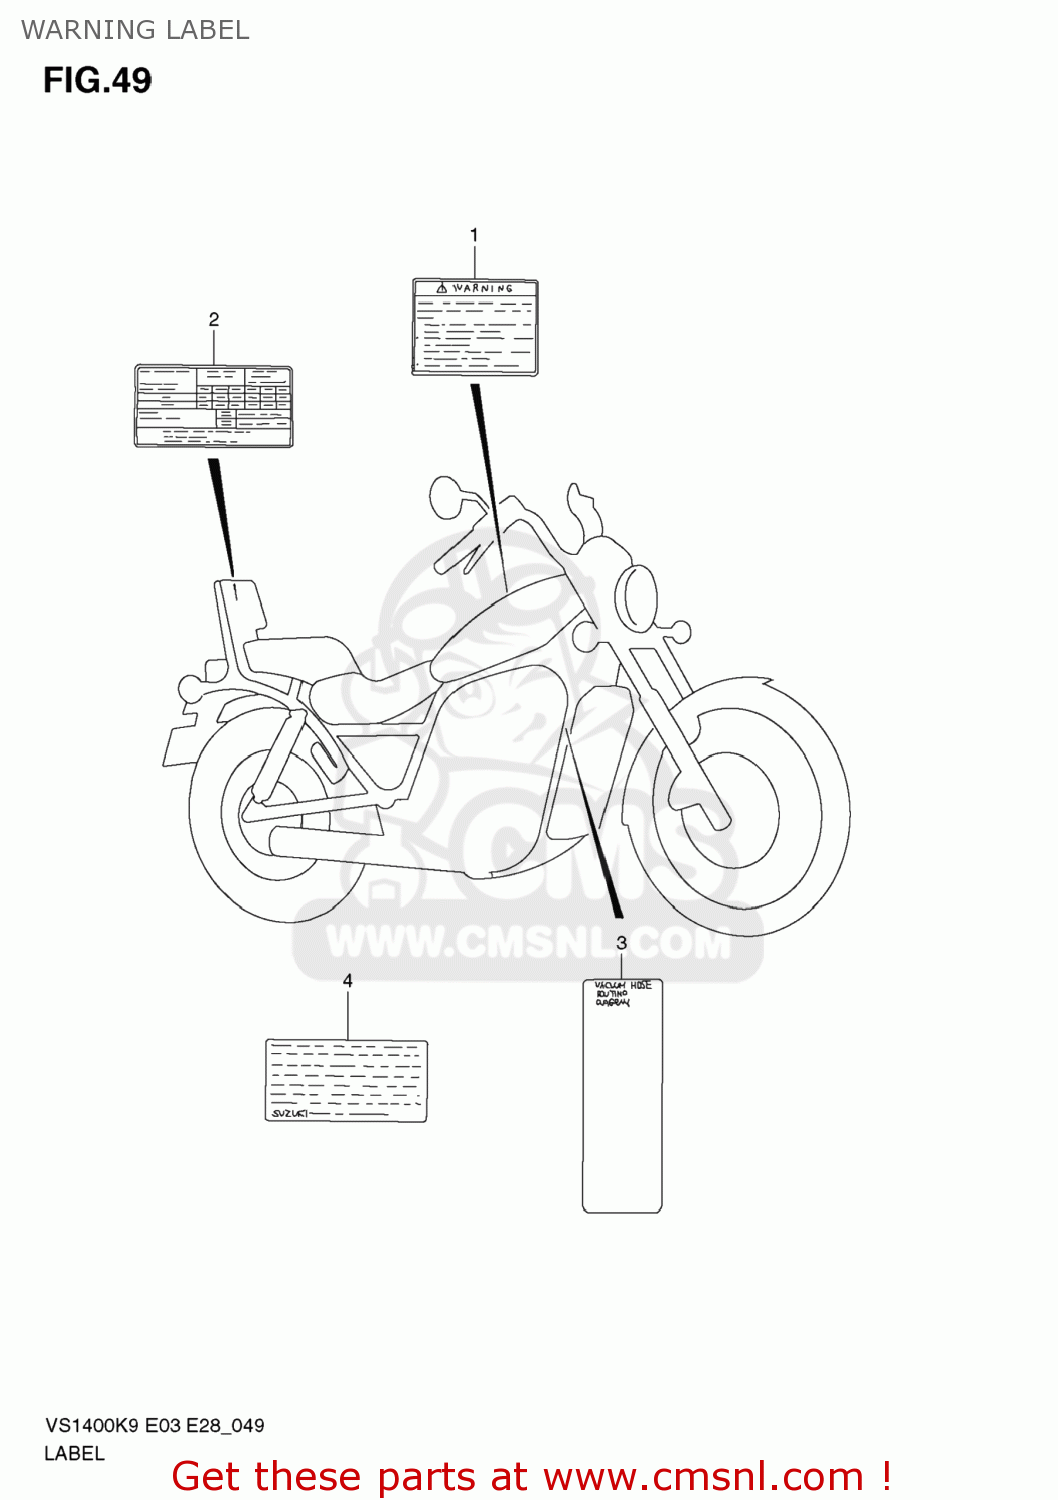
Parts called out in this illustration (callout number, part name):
1	LABEL,GENERAL WARNING
2	LABEL,TIRE INFORMATION
3	LABEL,VACUUM HOSE ROUTING
4	LABEL,MANUAL NOTICE
5	MANUAL,OWNER'S
